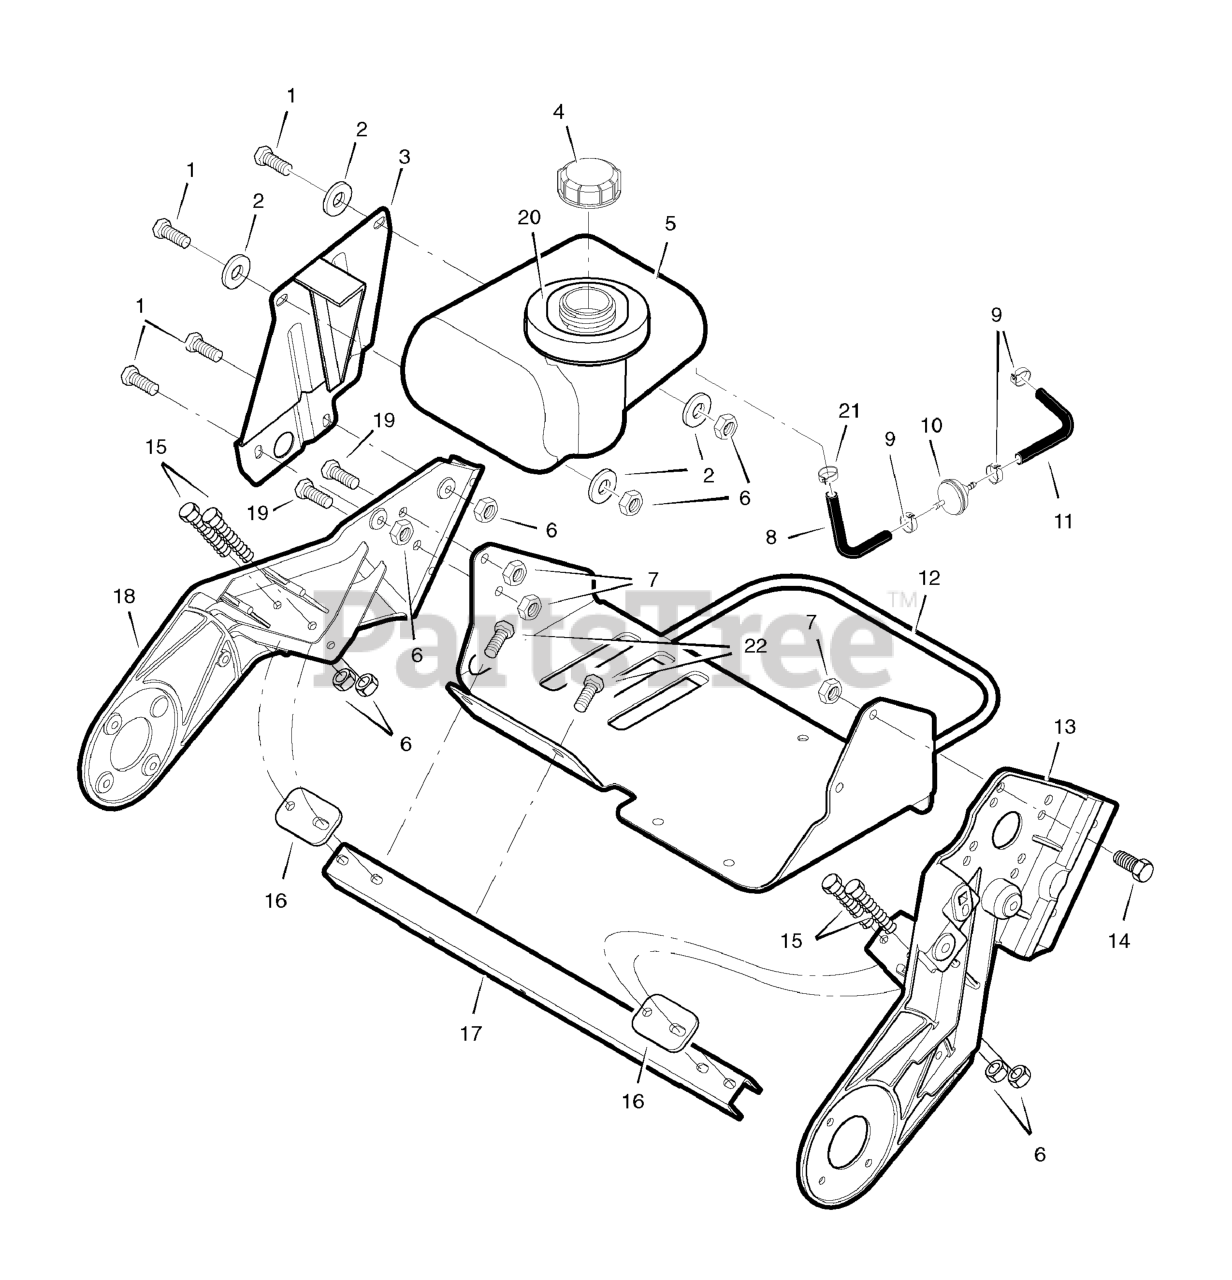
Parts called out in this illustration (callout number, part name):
1	Screw 1/4-20 x .75
2	Washer
3	Bracket, Fuel Tank
4	Cap, Fuel Tank
5	Tank, Fuel
6	Nut, Hex 1/4-20
7	Nut, Hex 5/16-18
8	HOSE, FUEL 12 INCHES
9	Clamp, Fuel Line
10	Filter, Fuel Line
11	Tubing, Fuel Line
12	Cradle Assembly, Engine
14	Screw, 5/16-18 x .63
15	Screw, 1/4-20 x 2.00
16	Plate, Mounting Support
17	Support, Frame
18	Frame, RH
19	Screw, 5/16-18 x 0.75
20	Ring, Foam
21	Clamp, Fuel Line -Screw Type
22	Screw, 1/4-20 x .625
